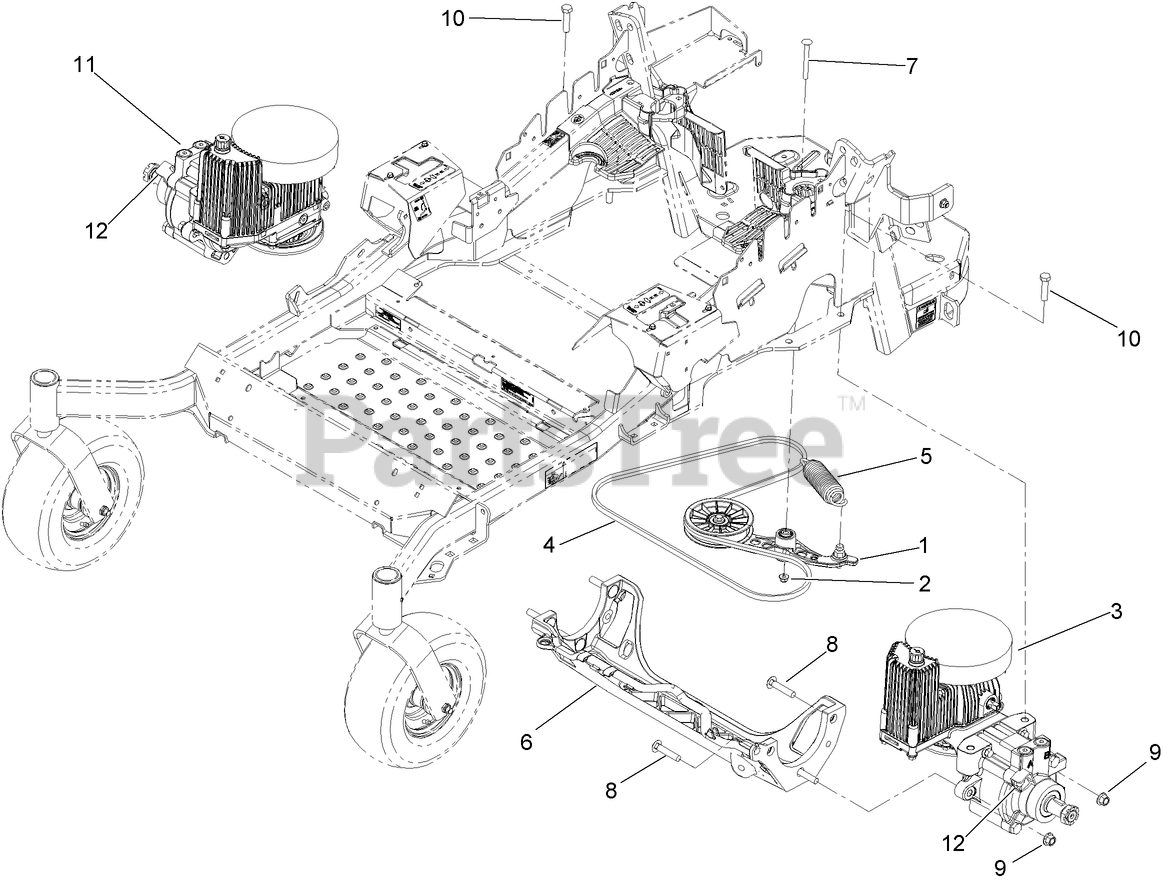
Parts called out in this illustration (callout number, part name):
1	PUMP IDLER ASM
2	NUT-FLANGE, NI
3	LH HYDRO ASM (16cc W/SHOCK)
4	BELT
5	EXTENSION-SPRING
6	CRADLE-HYDRO
7	BOLT-CARRIAGE
8	SCREW-CARR
9	NUT-LOCK
10	SCREW-HH
11	RH HYDRO ASM (16cc W/SHOCK)
12	BRACKET-ANCHOR, CABLE
